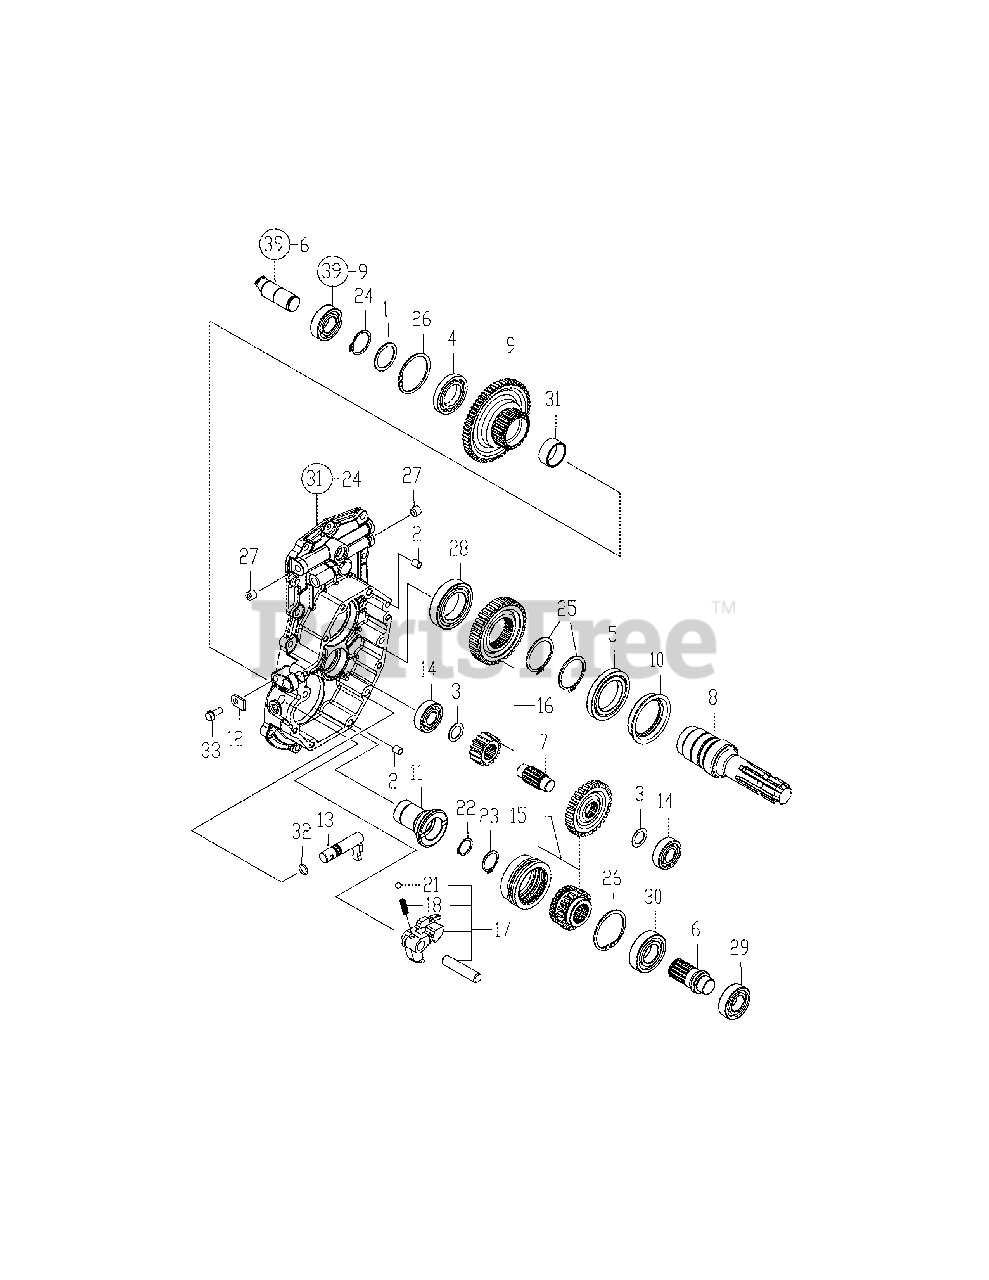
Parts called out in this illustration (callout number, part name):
1	Spacer, Clutch Shaft
2	Collar, 8X10X11.5
4	Bearing, 16007
5	Bearing, 16010
6	Shaft, Rear Pto
7	Shaft, Rear Pto Idle
8	Rear Pto Shaft
9	Gear, Pto Z=62 B
10	Seal, Tcfy557214
11	Collar, Spline
13	Shaft, Mbr Change
14	Bearing, 6204Rsh2
15	Gear Kit, 20-29
16	Gear Kit, 14-35
28	Bearing, 6009 Ntn
29	Bearing, 6205 Ntn
30	Bearing, 6206 Ntn
31	Needle, 354017
32	Packing, P 12.5
